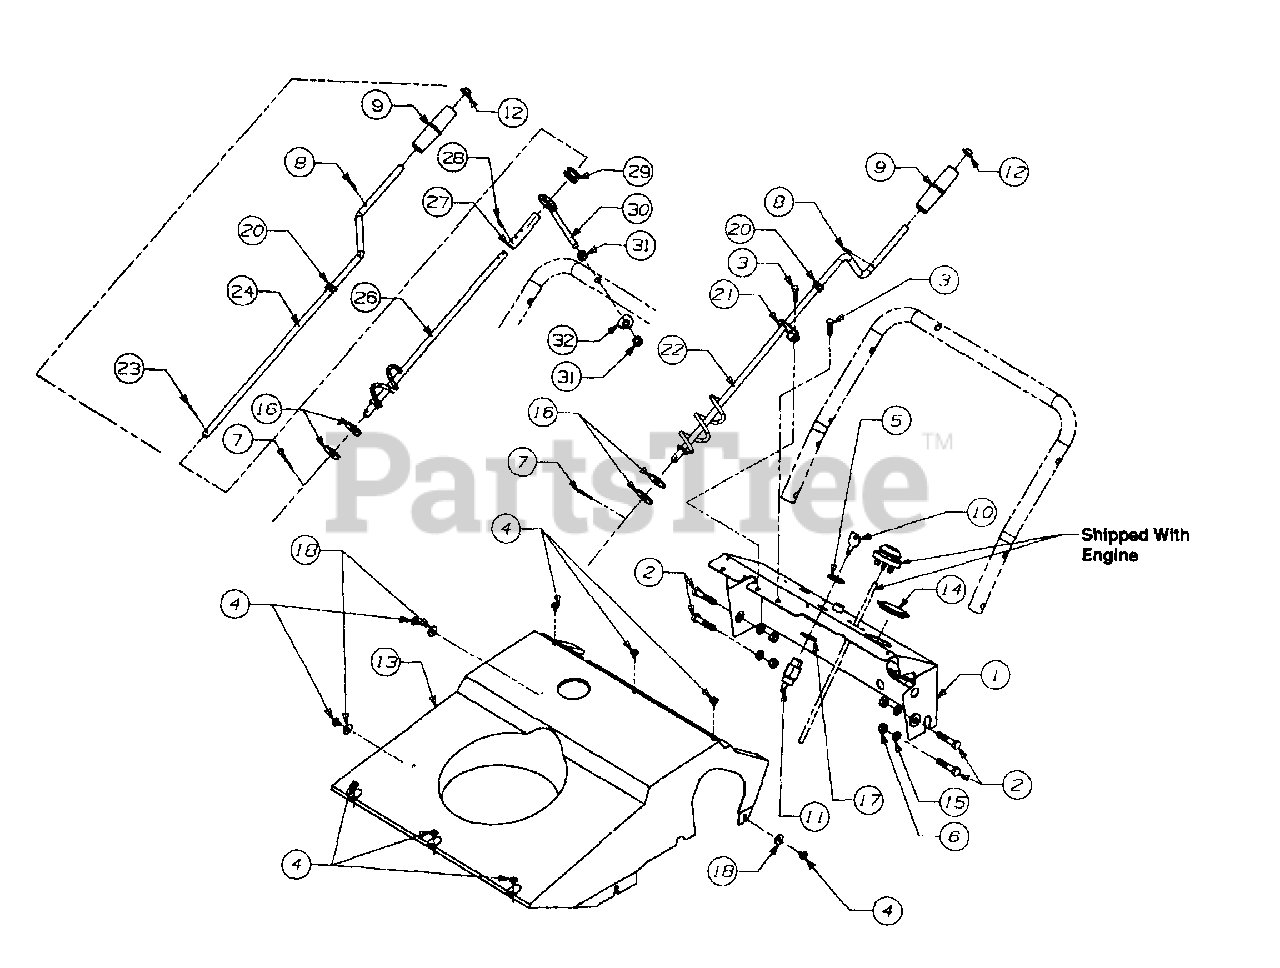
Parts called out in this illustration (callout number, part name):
3	Hex Tap Screw
4	Hex Tap Screw
7	Cotter Pin
9	Chute Crank Knob
10	Key - Ignition
11	Switch - Key
14	Plug
15	Lock Washer
16	Flat Washer
17	Internal Lock Washer
18	Flat Washer
20	Bushing
21	Bracket, Chute Crank
22	Crank Assembly, Chute
23	Cotter Pin
29	Grommet - Rubber
30	Eyebolt - Chute Crank
31	Nut - Hex
32	Washer - Saddle
